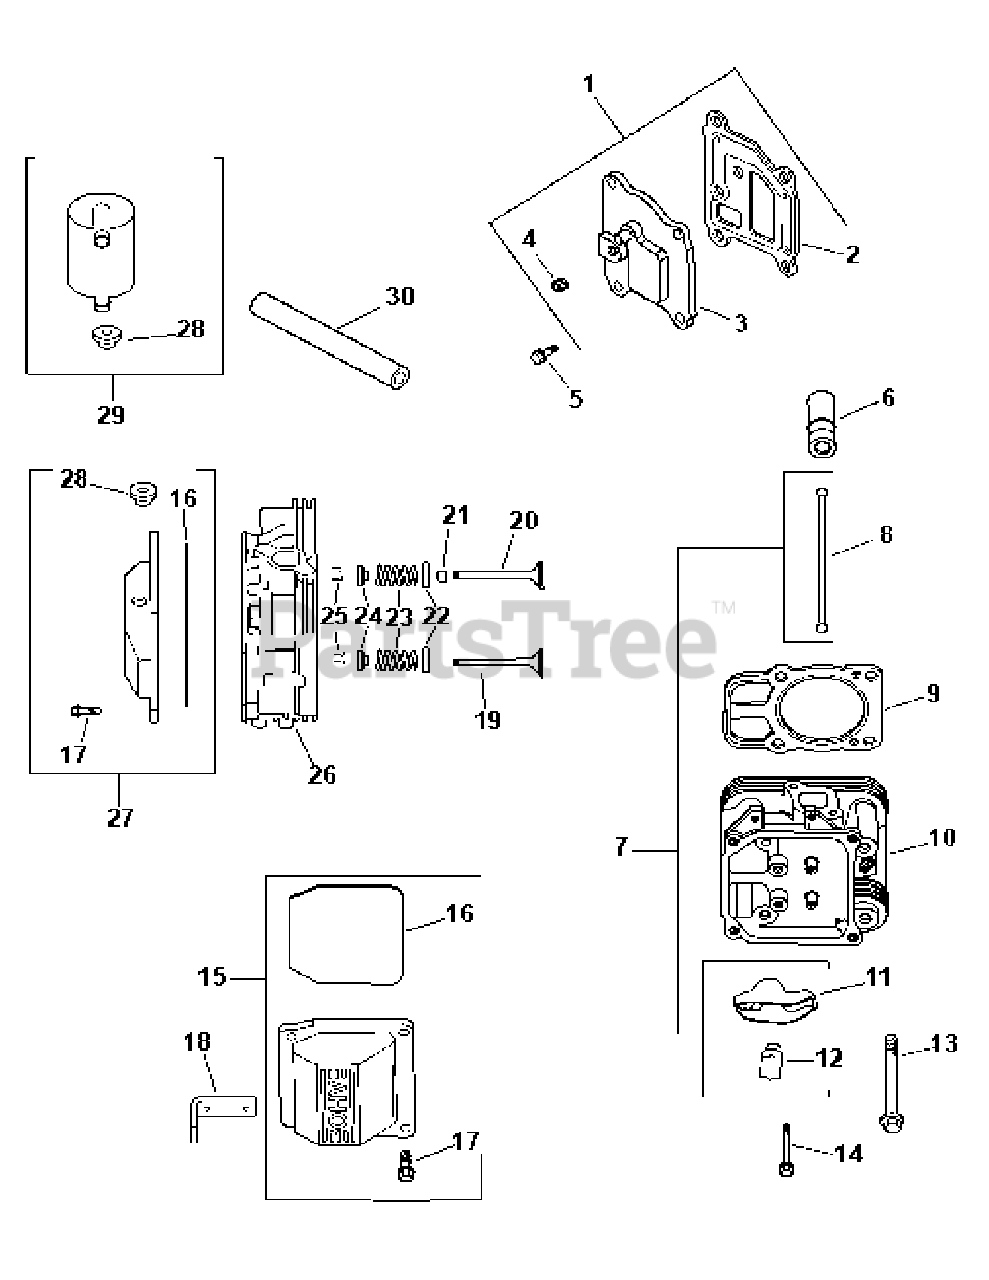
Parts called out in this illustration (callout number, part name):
1	Breather Cover Kit
2	Brather Gasket
3	Breather Cover
4	1/8" Pipe Plug
5	Hex Flange Screw
6	Valve Lifter
7	Valve TrainKit
9	Cylinder Head Gasket
10	Cylinder Head Assembly #2
12	Rocker Arm Pivot
13	Hex Flange Screw
14	Rocker Arm Pivot Screw
15	Rocker Cover Kit
16	O-Ring
17	Hex Flange Screw
18	Lifting Strap
19	Exhaust Valve
19	Exhaust Valve (.25)
20	Intake Valve
20	Intake Valve (.25)
21	Valve Stem Seal
23	Valve Spring
24	Valve Spring Retainer
25	Retainer Kit
26	Cylinder Head Assembly #1
27	Rocker Cover (Separator) Kit
28	Rubber Grommet
29	Breather Separator Kit
30	Breather Hose
